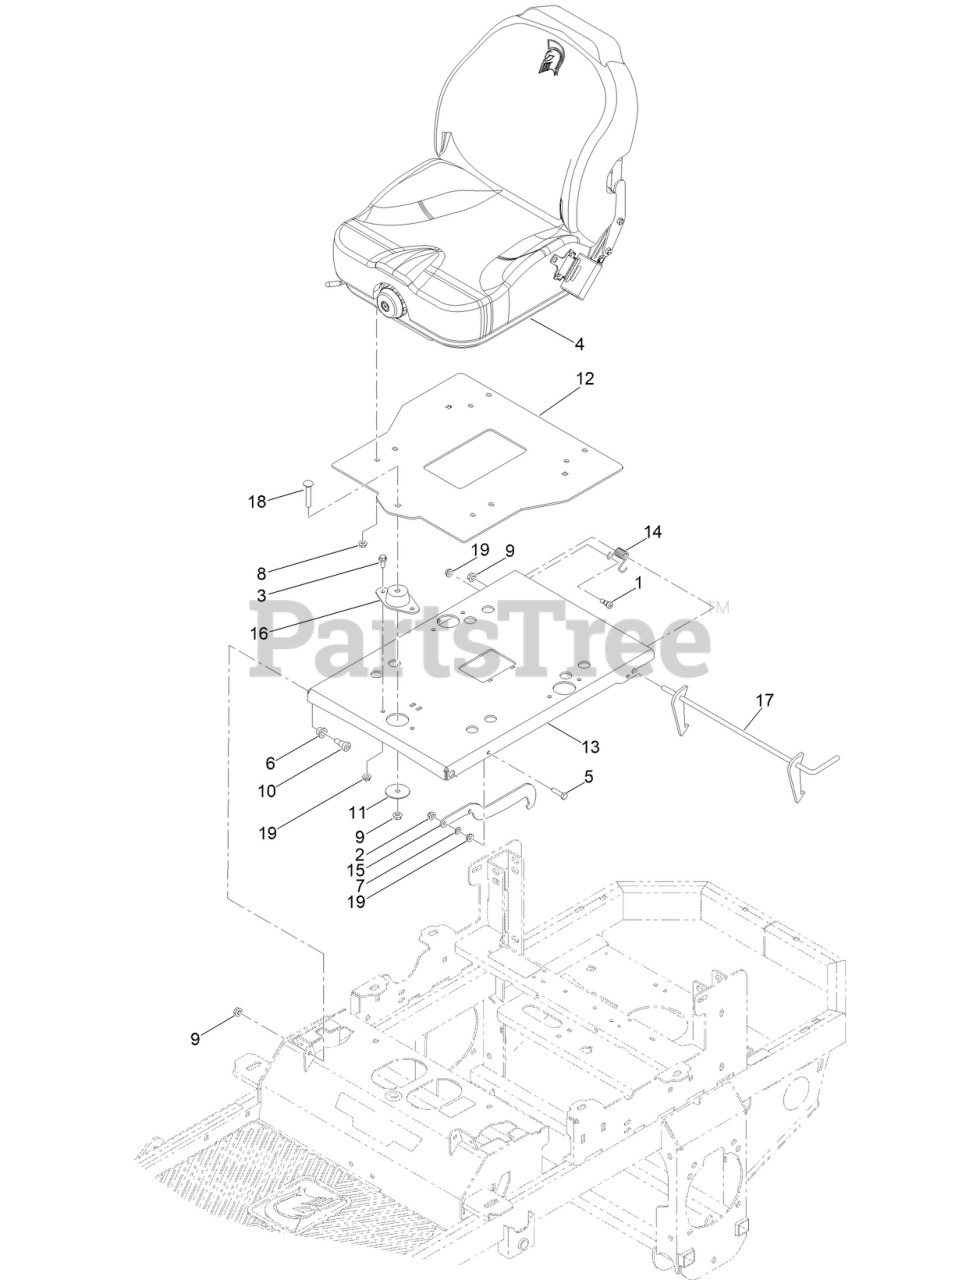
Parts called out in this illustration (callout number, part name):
1	SCREW-HSH
2	NUT-HF, NI
3	SCREW-HHF
4	SEAT-SUSP
5	SCREW-HH
6	1/2IN ID X 5/8IN OD X 1/2IN FLANGE BUSH
7	.312IDX.625ODX.062 THK THRUST BRG OI BRZ
8	5/16-18 NYLON INSERT FLANGE L/NUT ZC
10	1/2 X 1/2 SOCKET SHOULDER BOLT ZC YELLOW
11	3/8 X 2IN OD FENDER WASHER YZ
12	2019 UPGRADE SEAT PLATE
13	ASM, PLATE-SEAT BASE UPGRADE W/ DECAL
13	2019 SEAT BASE PLATE
14	MWR SEAT LATCH SPRING
15	MWR SEAT LATCH HOOK BLACK
16	FLOATING SEAT DAMPER-STIFFER
17	MWR SEAT LATCH RELEASE ASSY ABC
18	SCREW-CARR
